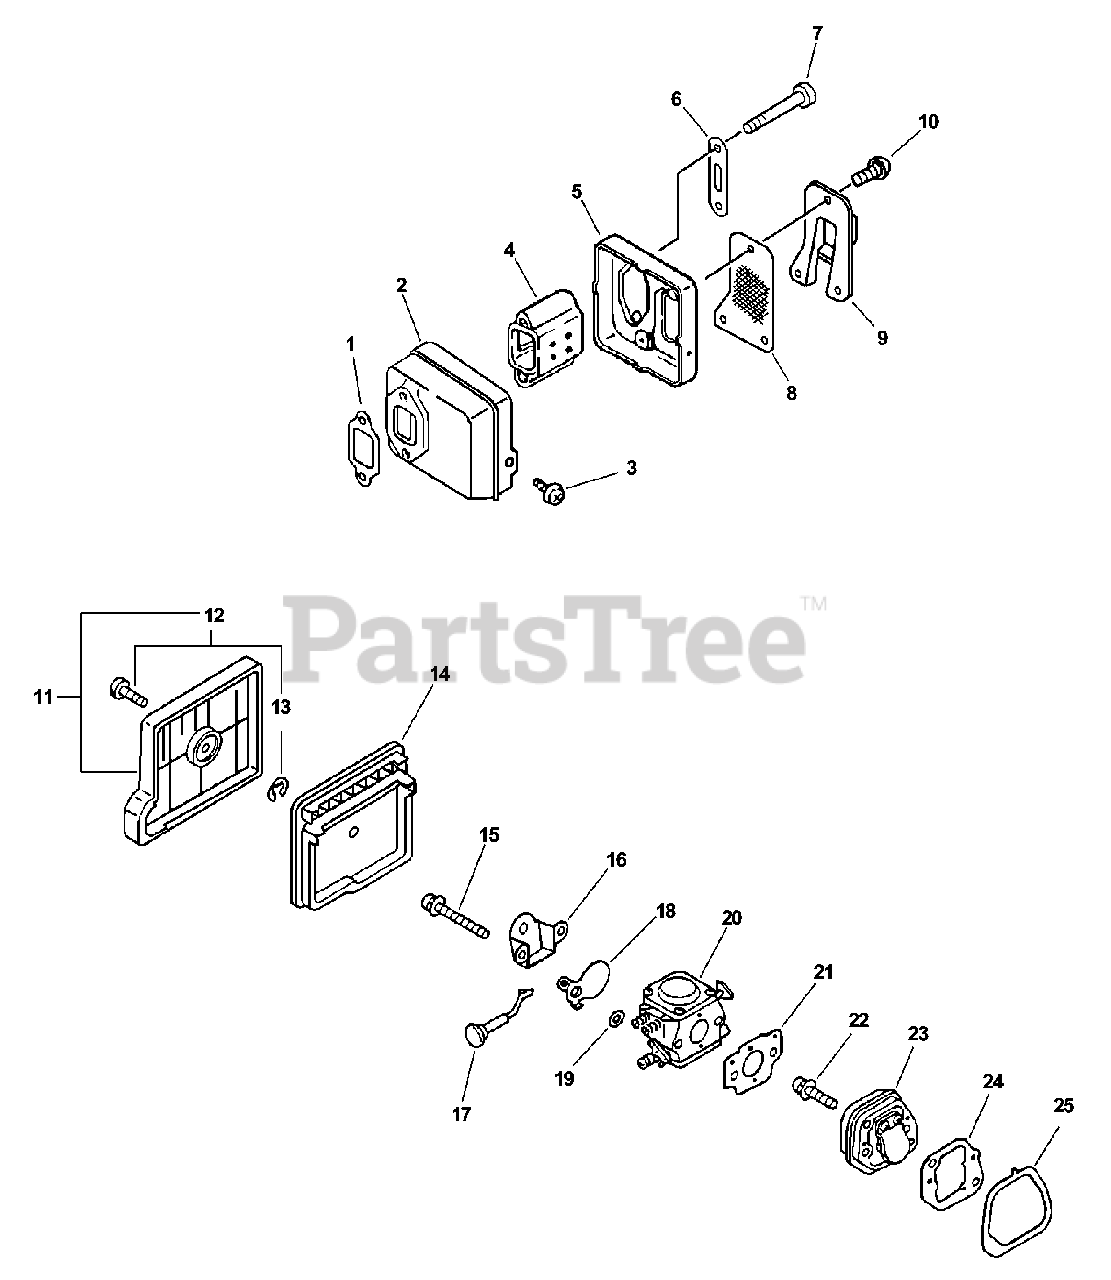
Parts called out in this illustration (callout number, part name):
1	GASKET, MUFFLER
3	SCREW TAPPING 4×8
4	SILENCER
5	COVER, MUFFLER
6	PLATE, EYE
7	BOLT 6 MM
8	SCREEN, SPARK ARRESTER
9	COVER, MUFFLER
10	SCREW TAPPING 4×8
11	COVER ASSY, AIR FILTER
12	THUMBSCREW
13	E-RING 4
14	FILTER, AIR
15	SCREW 5×45
16	PLATE, PREVENT
17	ROD, CHOKE
18	SHUTTER, CHOKE
19	WASHER 5.5×8×0.8
20	CARBURETOR - WT-589
21	GASKET, INTAKE
22	SCREW 5×18
23	INSULATOR KIT
24	GASKET, INTAKE
25	SEAL, INTAKE
